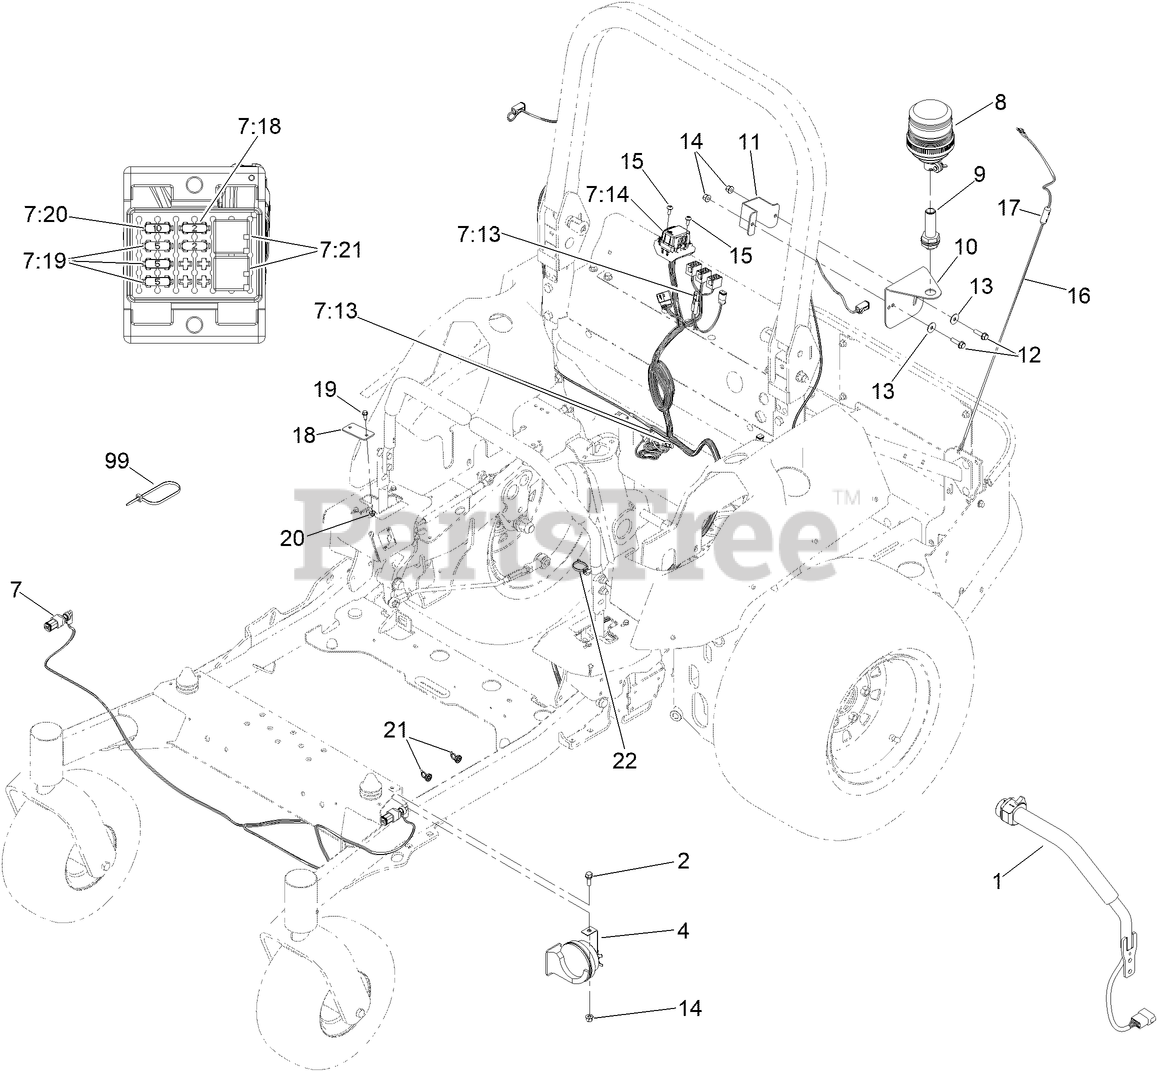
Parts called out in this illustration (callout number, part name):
1	LH LEVER ASM
2	SCREW-HHF
7	HARNESS-WIRE, EU LIGHT KIT
7:13	CAP-PLUG
7:14	COVER-FUSEBLOCK
7:18	FUSE-MINI BLADE, 2 AMP
7:19	FUSE-MINI BLADE, 5 AMP
7:20	FUSE-MINI BLADE, 10 AMP
7:21	RELAY-MICRO
8	LIGHT-BEACON ASM
9	SOCKET-BEACON
10	BRACKET,BEACON
11	CLAMP-50MM
12	SCREW-HHF
13	WASHER-PLAIN
14	NUT-FLANGE, NI
15	SCREW-SOC, HD
16	HARNESS-WIRE
17	FERRITE, EMC SUPPRESION
18	PLATE - SPEED LIMITER
19	SCREW-HWH
20	NUT-HF
21	MOUNT-TIE WRAP, MAGNETIC
22	CLIP-HARNESS. EDGE, W/TIE-WRAP
99	CLIP-TIE
99	TIE-CABLE
